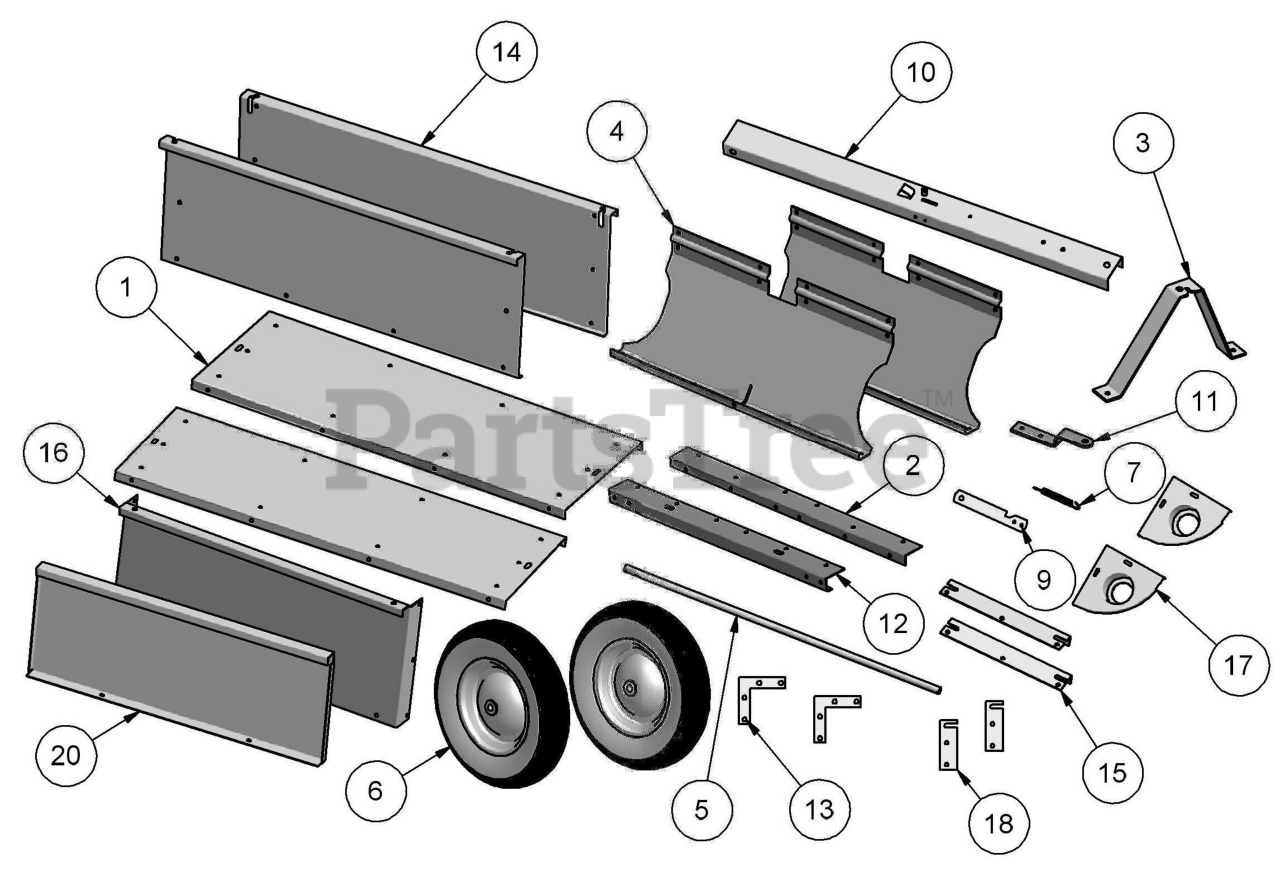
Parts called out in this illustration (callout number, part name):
1	BOTTOM PANEL
2	FRONT CROSS BRACE
3	TONGUE SUPPORT
4	WHEEL AXLE SUPPORT
5	WHEEL AXLE
6	WHEEL/TIRE ASSEMBLY
7	LATCH SPRING
9	TONGUE LATCH
10	HITCH TONGUE
11	HITCH PIN BRACKET
12	REAR CROSS BRACE
13	REAR CORNER BRACKET
14	SIDE PANEL
15	REAR CORNER BRACE
16	FRONT PANEL
17	FRONT CORNER BRACE
18	TAILGATE LATCH
20	TAILGATE
